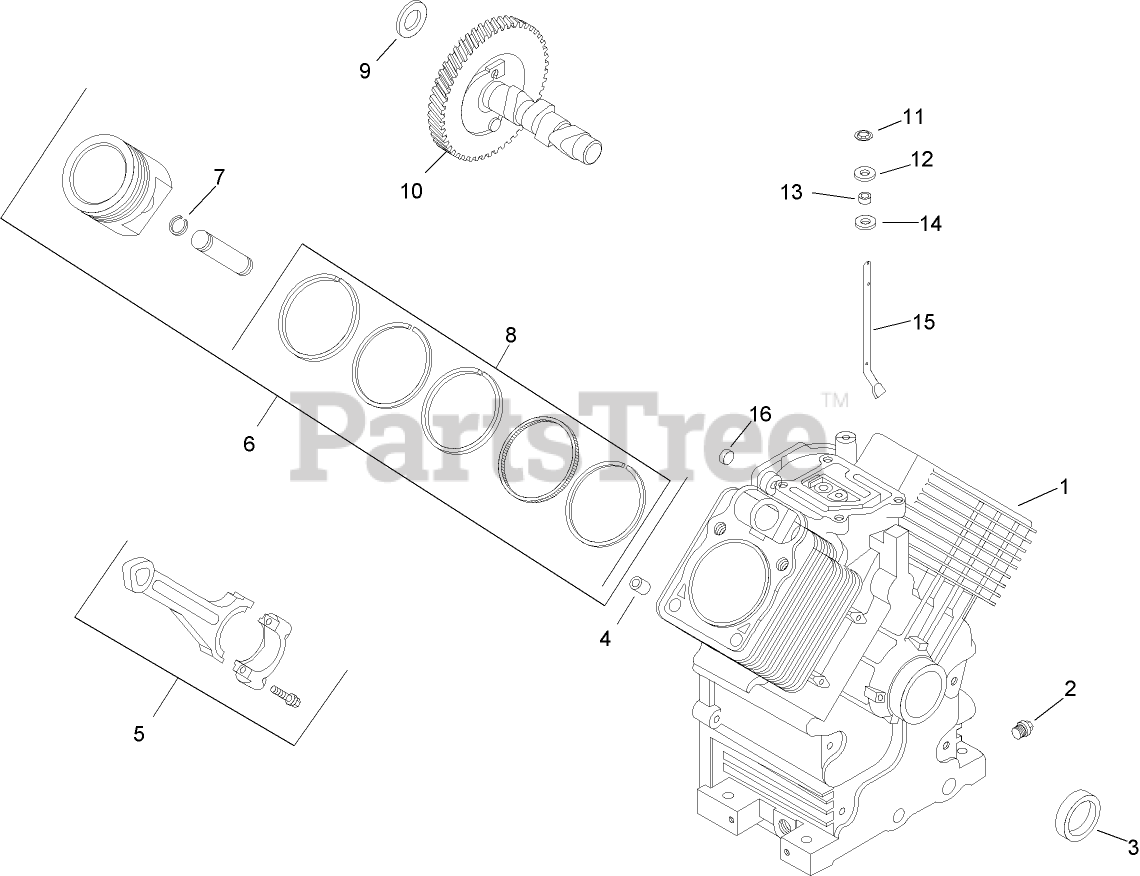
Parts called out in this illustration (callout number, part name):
2	PLUG-PIPE HEAD, 3/8
3	SEAL-OIL
4	Pin-Locating
5	Rod-Connecting (Standard)
5	Rod-Connecting (.25)
6	Piston ASM (Std.) (Includes 7,8)
6	Piston ASM (.08)
6	Piston ASM (.25)
6	Piston ASM (.50)
7	RETAINER-PIN, PISTON
8	RING SET (STD AND .08)
8	Ring Set (.25)
8	Ring Set (.50)
9	SHIM-CAMSHAFT (RED .032)
9	SHIM-CAMSHAFT (BLACK .04)
9	SHIM-CAMSHAFT (WHITE .028)
9	SHIM-CAMSHAFT (BLUE .03)
9	SHIM-CAMSHAFT (YELLOW .034)
9	SHIM-CAMSHAFT (GREEN .036)
9	SHIM-CAMSHAFT (GRAY .038)
10	Camshaft Kit
11	RETAINER-RING
12	Washer-Plain (top)
13	SEAL-CROSS SHAFT, GOVERNOR
14	Washer-Flat (bottom)
15	SHAFT-CROSS, GOVERNOR
16	PLUG-CUP
